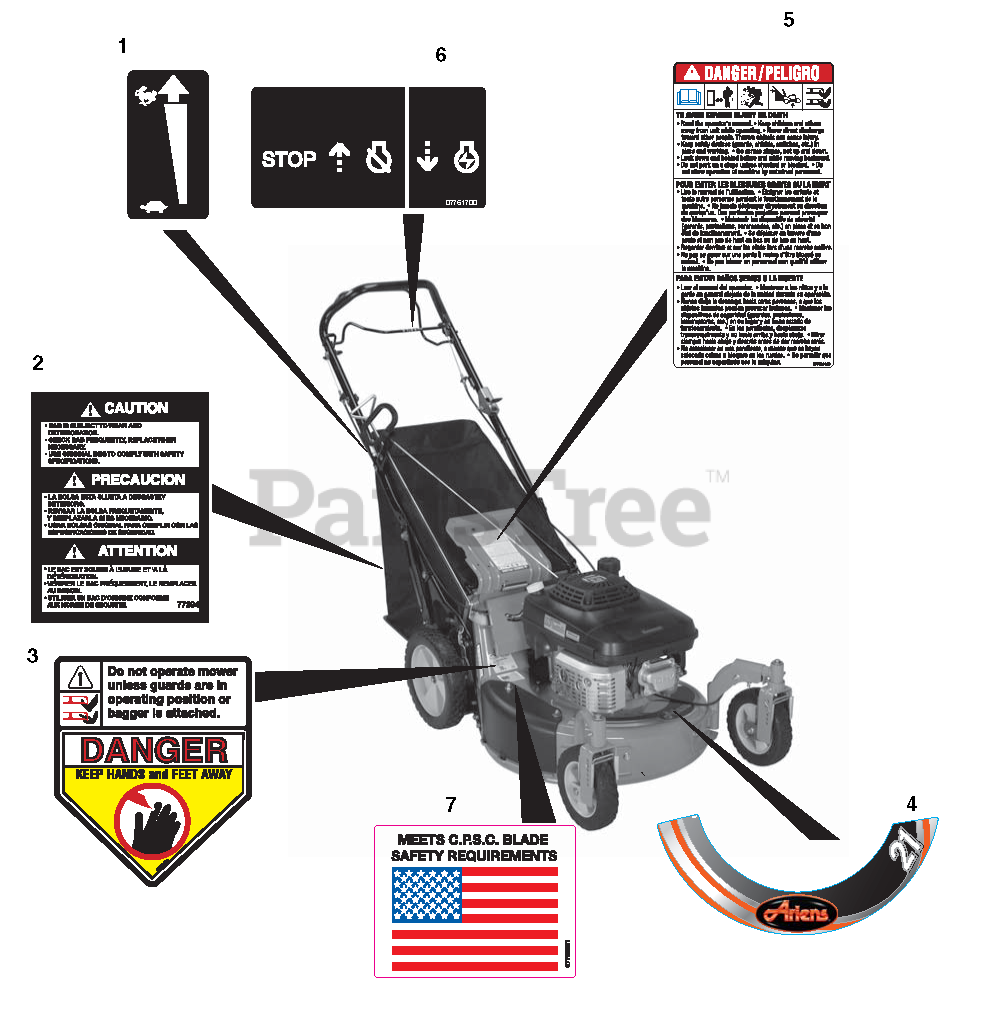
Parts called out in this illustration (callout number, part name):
1	DECAL-SPEED CONTROL
2	LABEL - BAGGER 21"
3	DECAL, CPSC DANGER
4	DECAL, ARIENS CLASSIC 21 DECK
5	DECAL, BILINGUAL DANGER
6	DECAL - ENGINE CONTROL
7	DECAL, CPSC/USA FLAG
